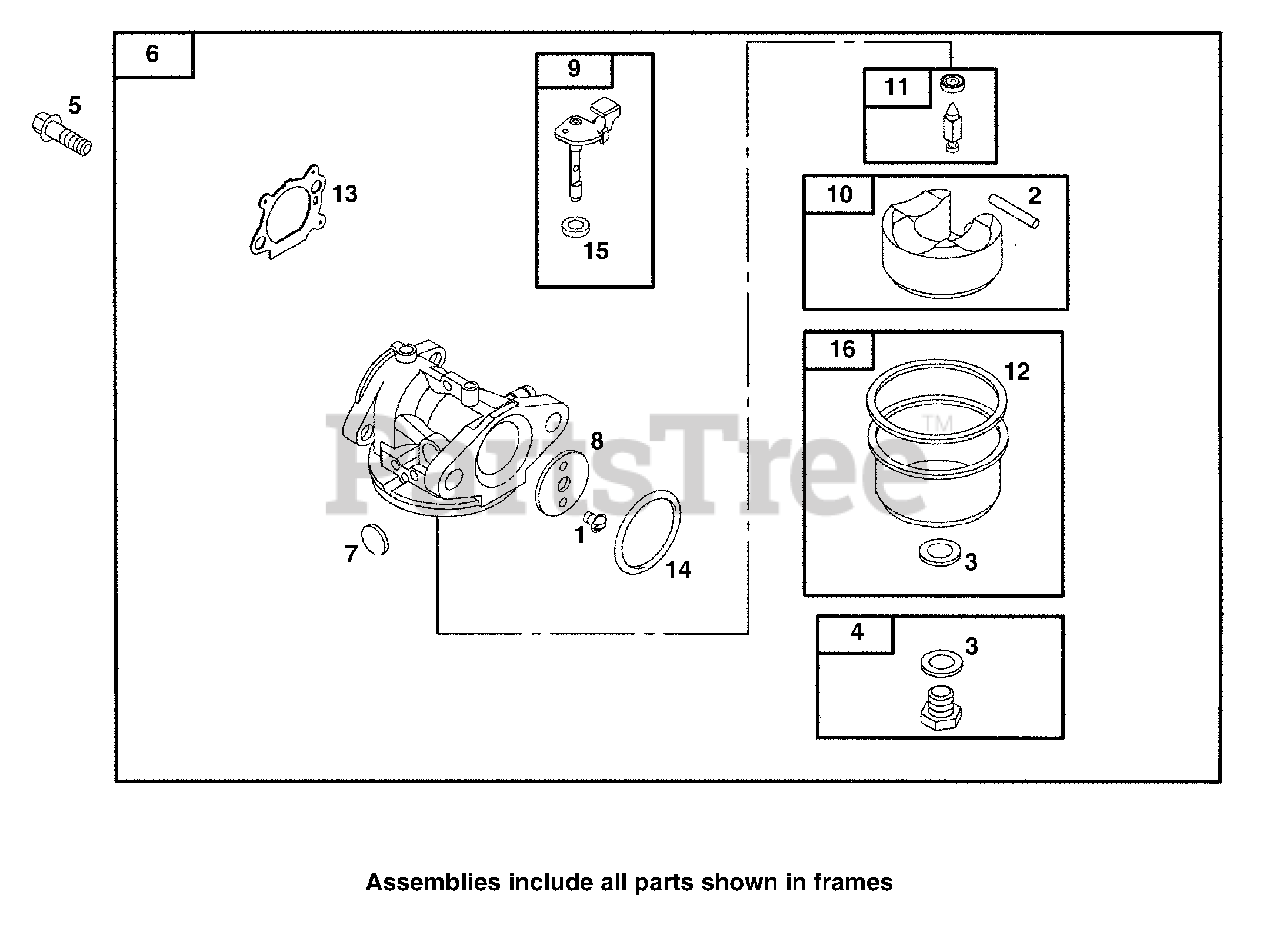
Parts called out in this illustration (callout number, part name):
1	Choke/Thread Screw
2	Float Hinge
3	Bowl Washer (Sold only in kit)
4	Main Jet (Standard)
5	Hex Screw
6	Carburetor
7	Welch Plug (Sold only in kit)
8	Throttle Valve
9	Throttle Shaft Kit
10	Carburetor Float
11	Needle/Seat Kit
12	Bowl Gasket (Sold only in kit)
13	Air Cleaner Gasket
14	Intake Manifold Seal
16	Float Bowl
